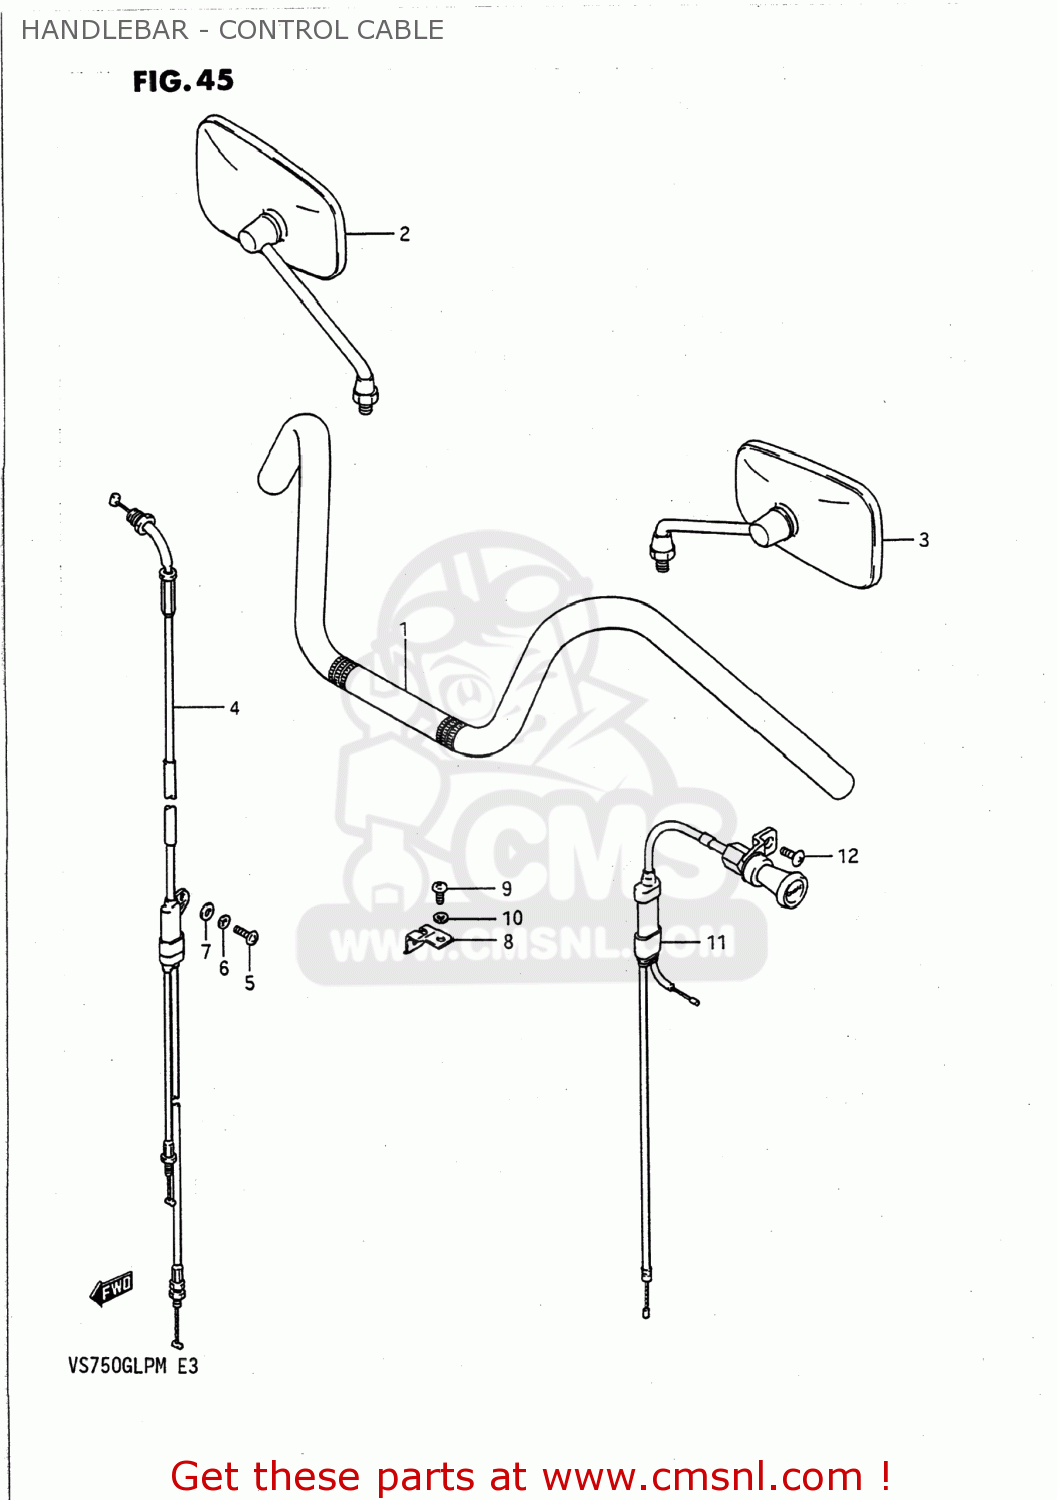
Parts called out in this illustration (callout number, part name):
1	HANDLEBAR
2	MIRROR ASSY,RR VIEW,R
3	MIRROR ASSY,RR VIEW,L
4	CABLE ASSEMBLY,THROTTLE
5	SCREW
6	LOCK WASHER
7	WASHER
8	CLAMP,THROTTLE CABLE
9	SCREW
10	LOCK WASHER
11	CABLE ASSEMBLY,STARTER
12	SCREW
